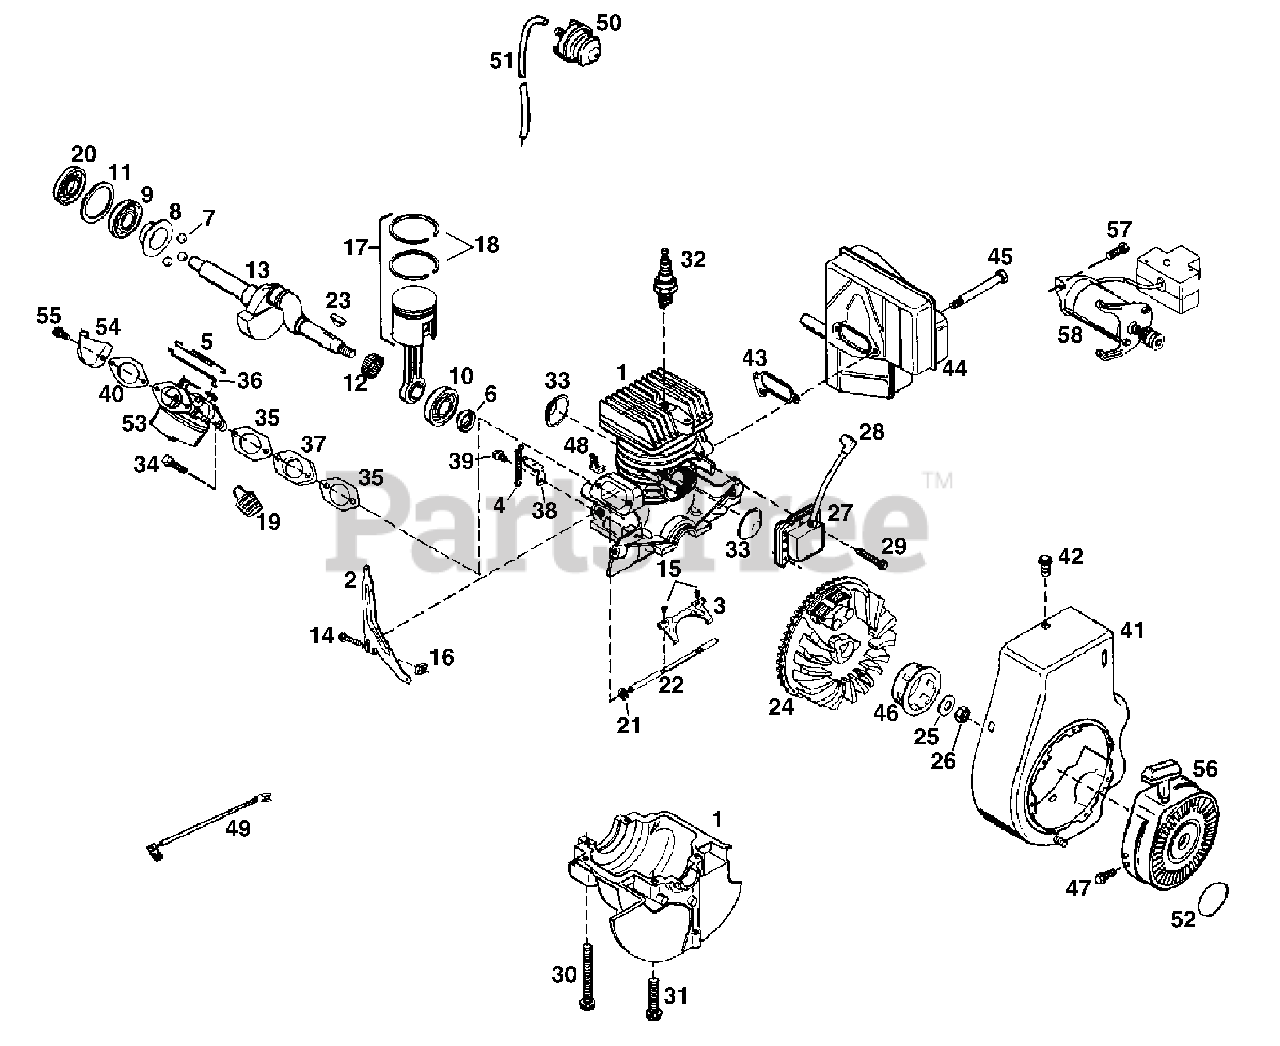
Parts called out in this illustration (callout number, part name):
1	Cylinder Ass’y
2	Governor Lever
3	Governor Lever
4	Extension Spring
5	Throttle Link Spring
7	Ball Bearing
8	Slide Ring
9	Ball Bearing
10	Ball Bearing
11	Bearing Retainer
12	Bearing Strip (31 Needles)
13	Crankshaft
14	Screw, 10-32 x 3/4".
15	Screw, 4-40 x 1/4".
16	Lock Nut, 10-32
17	Piston & Rod Ass’y
19	Control Knob
22	Governor Shaft
23	Flywheel Key
25	Bell Washer
26	Flywheel Nut
27	Solid State Ignition
28	Spark Plug Cover
29	Screw, Torx T-15, 10-24 x 15/16".
30	Screw, 5/16-18 x 2-3/16".
31	Screw, 5/16-18 x 1-5/8".
32	Resistor Spark Plug
33	Port Cover
34	Screw, 5/32 Allen, 1/4-20 x 5/8".
35	Carburetor Gasket
36	Governor Link
38	Control Lever
39	Screw, 8-32 x 1/2".
40	Air Cleaner Gasket
41	Blower Housing
42	Screw, 5/16-18 x 5/8".
43	Exhaust Gasket
45	Screw, 5/16-18 x 3-13/64".
46	Starter Cup
47	Screw, 8-20 x 21/64".
48	Wire Clip
49	Wire Harness
50	Primer Ass’y
51	Primer Line
52	Starter Decal
53	Carburetor
55	Screw, Torx T-25, 10-32 x 3/8".
56	Rewind Starter
57	Screw, Torx T-30, 1/4-20 x 1/2".
58	Electric Starter
